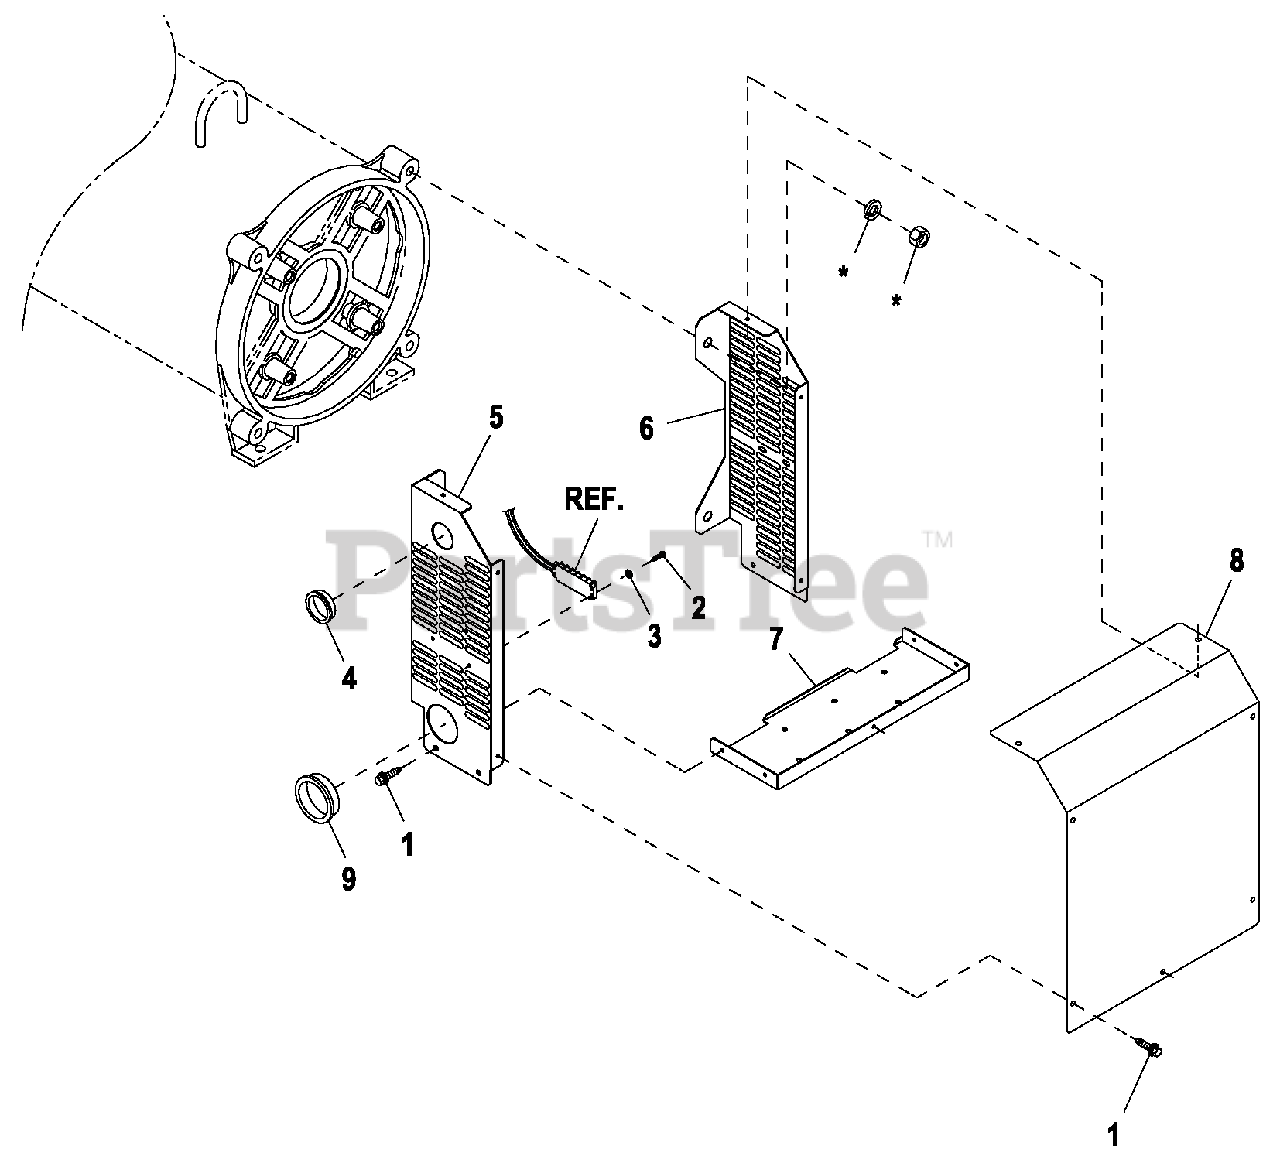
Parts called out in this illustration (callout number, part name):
1	SCREW THF M6-1 X 16 N WA Z/JS
2	SCREW PHTT #6-32 X 1/2 ZYC
3	WASHER LOCK #6
4	BUSHING SNAP S B -1750-22
5	SIDE LH EXCITER SHIELD
6	SIDE RH EXCITER SHIELD
7	BOTTOM EXCITER SHIELD
8	REAR COVER EXCITER SHLD
9	BUSHING SNAP S B -2.5-31
